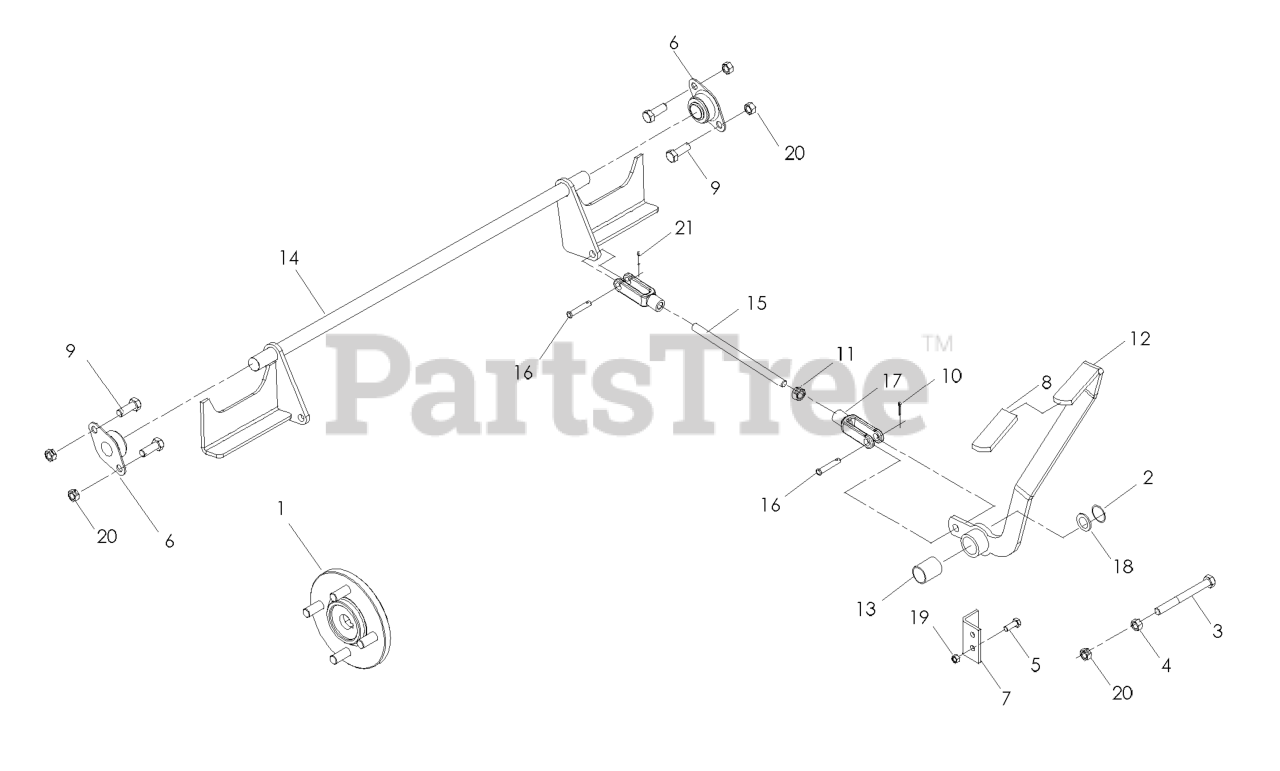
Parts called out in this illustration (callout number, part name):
1	HUB.WHEEL.ZTR
2	RETAINING RING, 7/8"
3	HCS 3/8C X 2 1/2
4	NUT 3/8C WHIZ
5	HCS 1/4C X 3/4 HCS
6	FLANGE BEARING
8	GRIP, PARK BRAKE
9	HCS 3/8-16X1.GRD.5.ZD
10	RP_COTTER PIN 1/8 X 3/4
12	BRAKE LEVER WLDMT
14	BRAKE SHAFT WLDMT
16	CLEVIS PIN 3/8 X 1 1/8
17	YOKE-3/8-24 PLTD
18	BSHG .875 X 1.375 X .074 ZD
19	NUT.1/4-20.HEX.NYLOC.ZD
20	NUT 3/8-16 NYLOC
